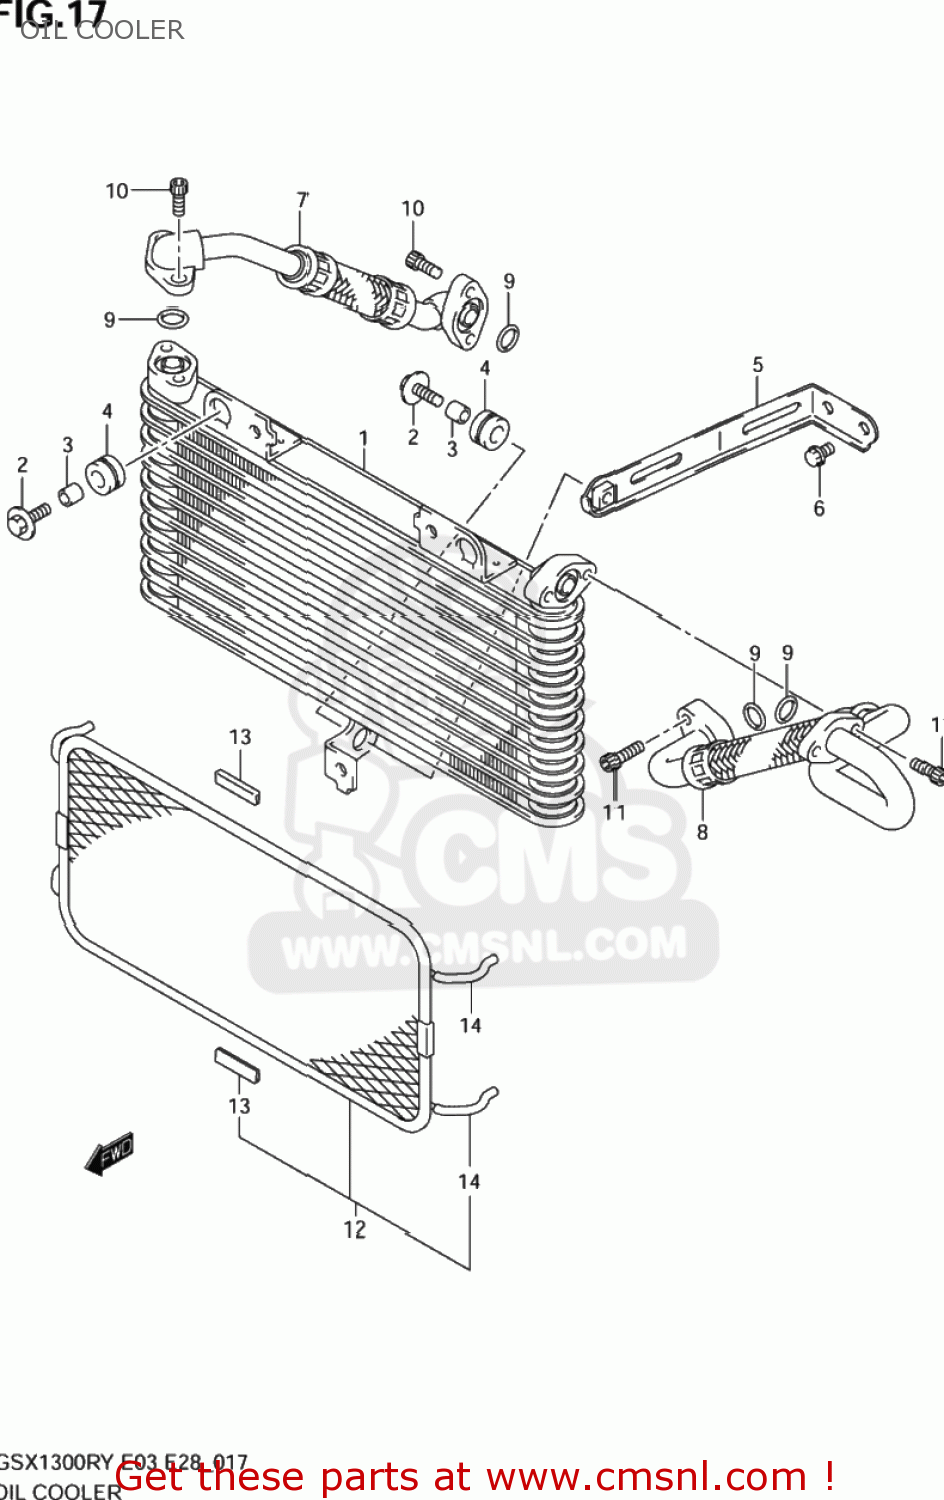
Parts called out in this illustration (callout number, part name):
1	COOLER ASSY,OI
2	BOLT(6X20)
3	SPACER(6.5X10X10)
4	CUSHION
5	BRACKET,OIL COOLER
6	BOLT
7	HOSE,OIL COOLER,R
8	HOSE,OIL COOLER,L
9	O RING(D:2.4,ID:11.8)
10	BOLT(6X20)
11	BOLT(6X20)
12	GUARD,OIL COOLER
13	PROTECTOR,CTR
14	HOSE(3X5X600)
